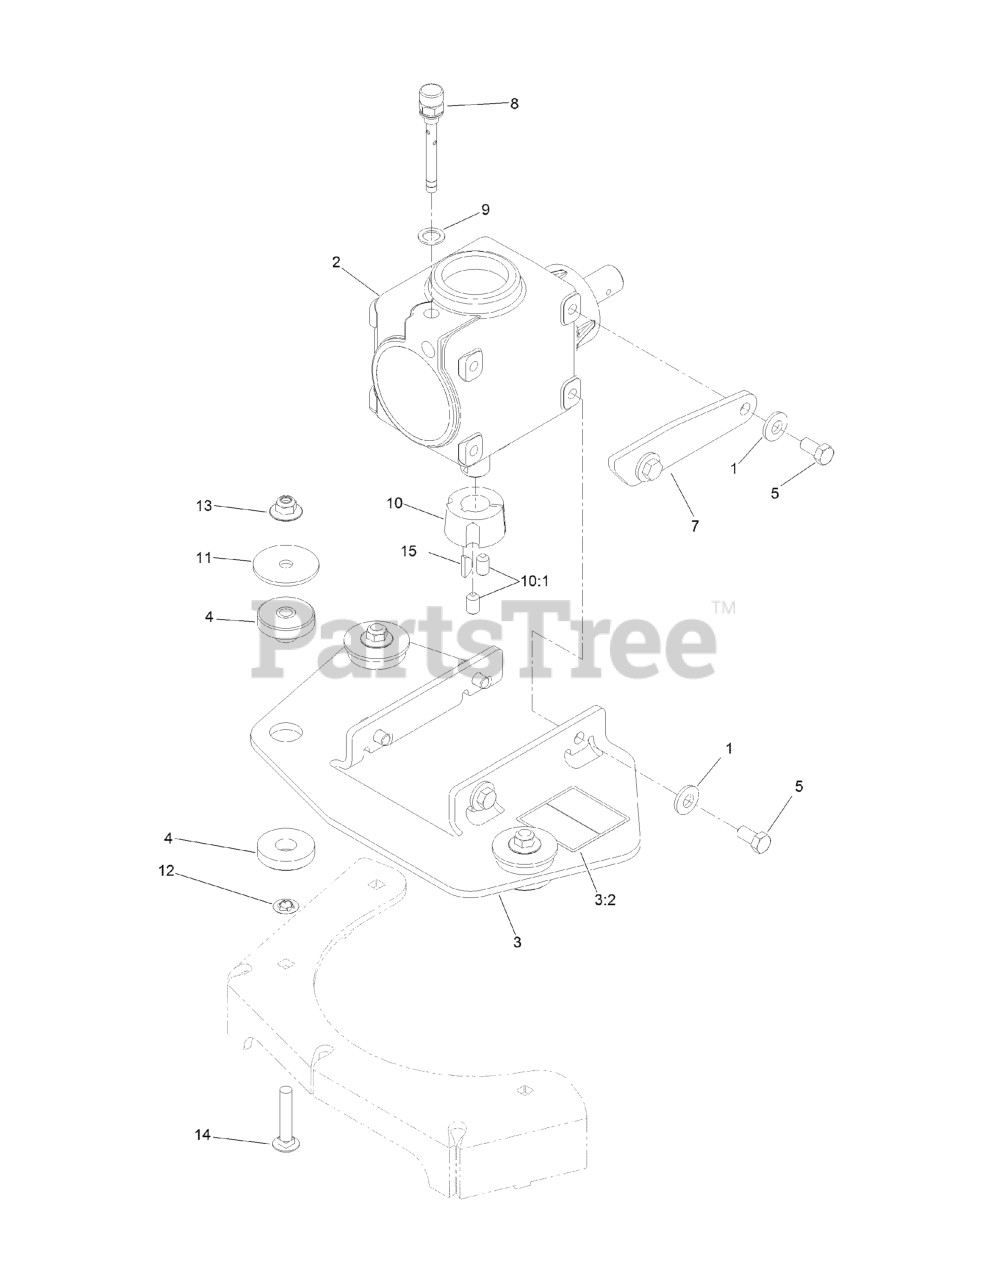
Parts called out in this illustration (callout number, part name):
1	WASHER-BELLEVILLE
2	Gearbox ASM
2	GEARBOX ASM
3	MOUNT-GEARBOX
3:2	DECAL-HAZARD, ENTANGLEMENT
4	MOUNT-ISO
5	SCREW-HH
7	STOP-GEARBOX
8	PLUG-BREATHER
10	BUSHING-TAPERLOCK
10:1	SCREW-SET
11	WASHER-FLAT
12	NUT-PUSH
13	Nut-Nyloc 3/8-16 Flg
14	SCREW-CARR
15	KEY-WOODRUFF
